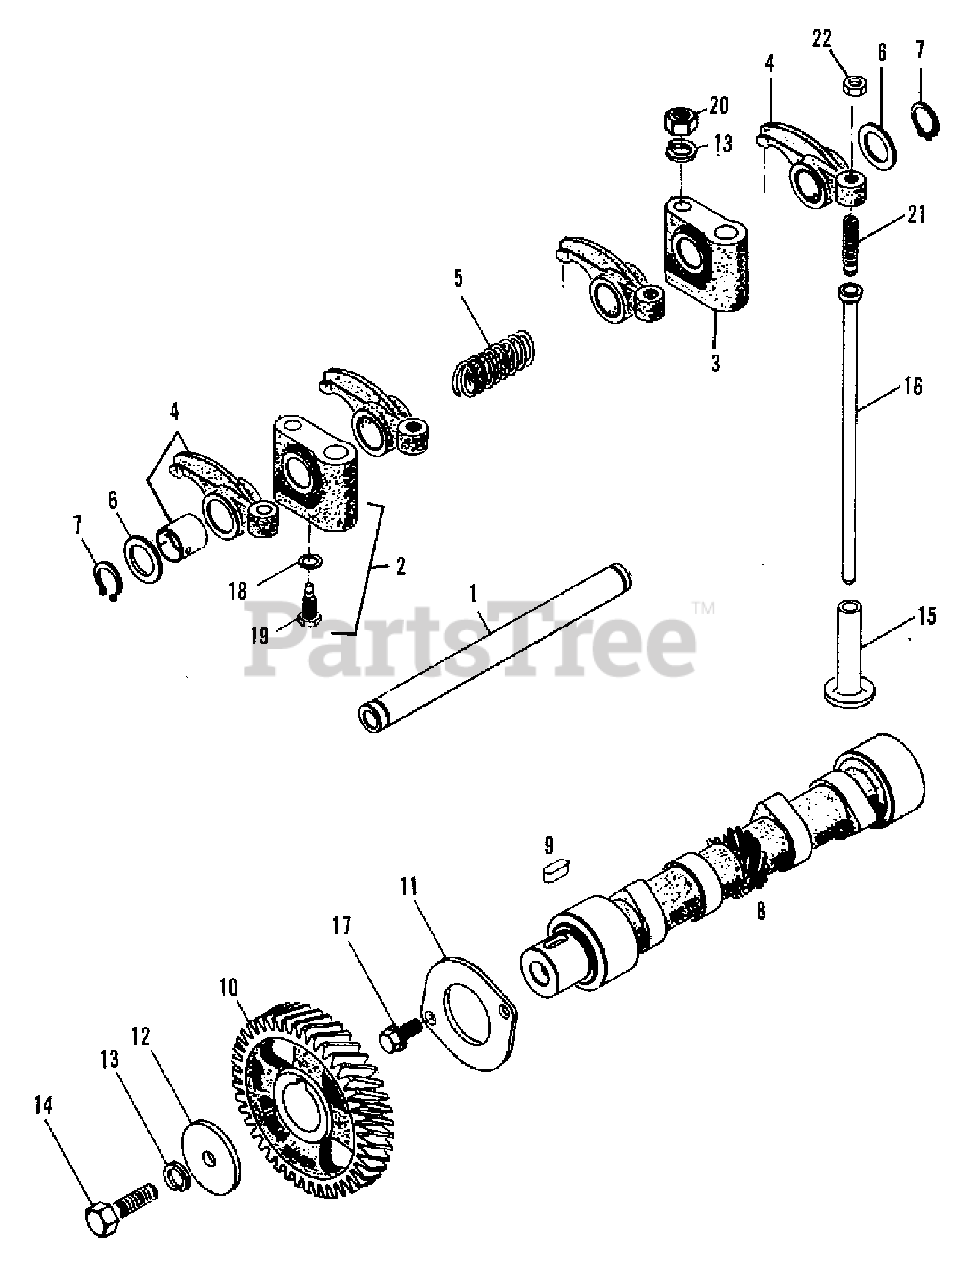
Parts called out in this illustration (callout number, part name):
1	SHAFT, rocker arm
2	BRACKET ASSEMBLY (Incl. Items 18, 19) support (front)
3	BRACKET , support (rear)
4	ARM ASSEMBLY, rocker
6	PLATE, rocker adjusting
9	KEY, camshaft gear
10	GEAR, camshaft
11	PLATE, thrust
12	WASHER, thrust
13	LOCKWASHER, M10
14	BOLT, M10 x 34
15	LIFTER, valve
16	ROD, push
17	CAPSCREW, M8 x 20 w/lockwasher
19	BOLT, M8 x 45 lock
20	NUT, bracket
21	BOLT, M9 x 39 rocker adjusting
22	NUT, lock
